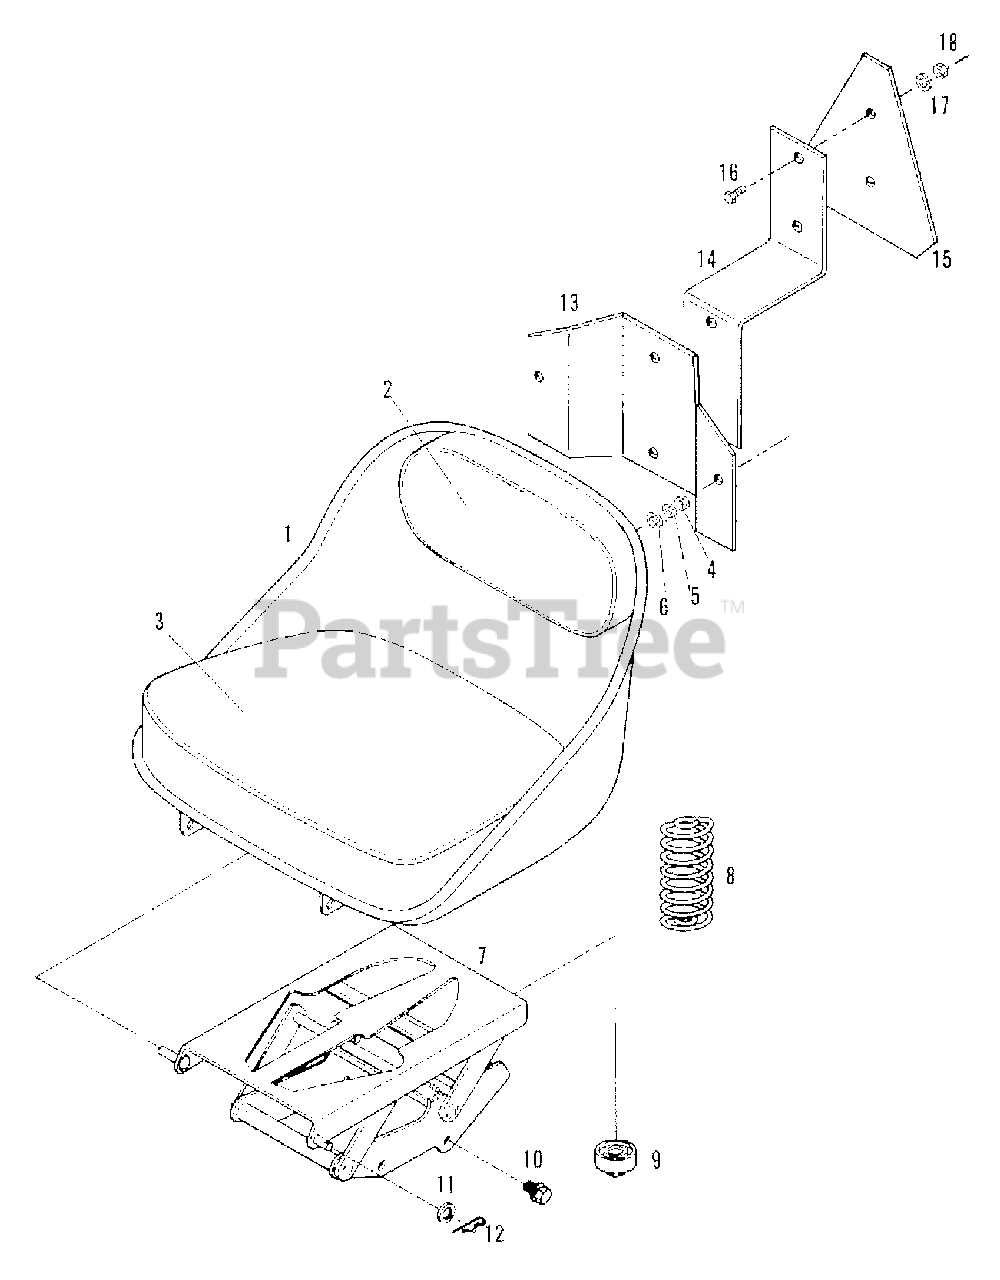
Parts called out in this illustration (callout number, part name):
1	FRAME, seat
2	CUSHION, back
3	CUSHION, seat
5	LOCKWASHER, M6
7	FRAME, seat
8	SPRING, seat cushion
10	CAPSCREW, M10 x 20
12	CLIP, hair pin
13	BRACKET, lower SMV
14	BRACKET, upper SMV
15	SMV EMBLEM
16	CAPSCREW, 1/4NC x 3/4
17	LOCKWASHER
18	NUT, 1/4NC
